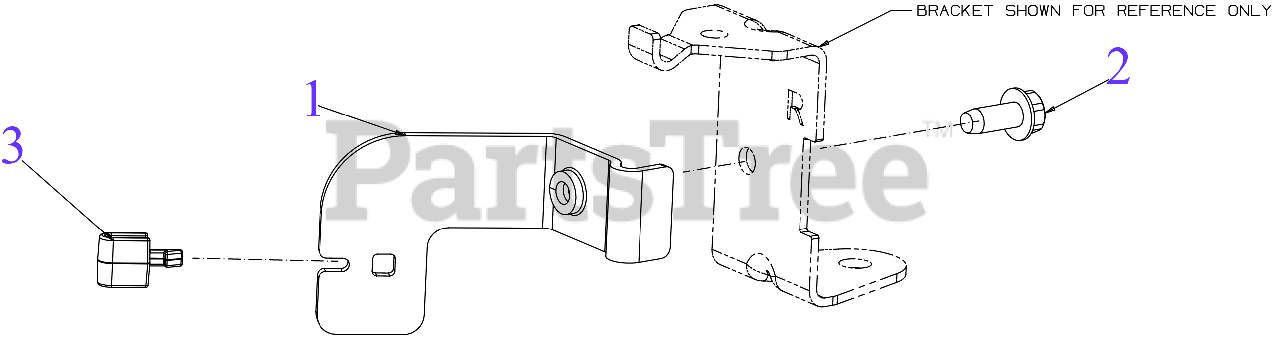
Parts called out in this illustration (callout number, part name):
1	CLUTCH STOP BRACKET
2	SCREW M8-1.25 x .750
3	CLUTCH BRACKET GROMMET
